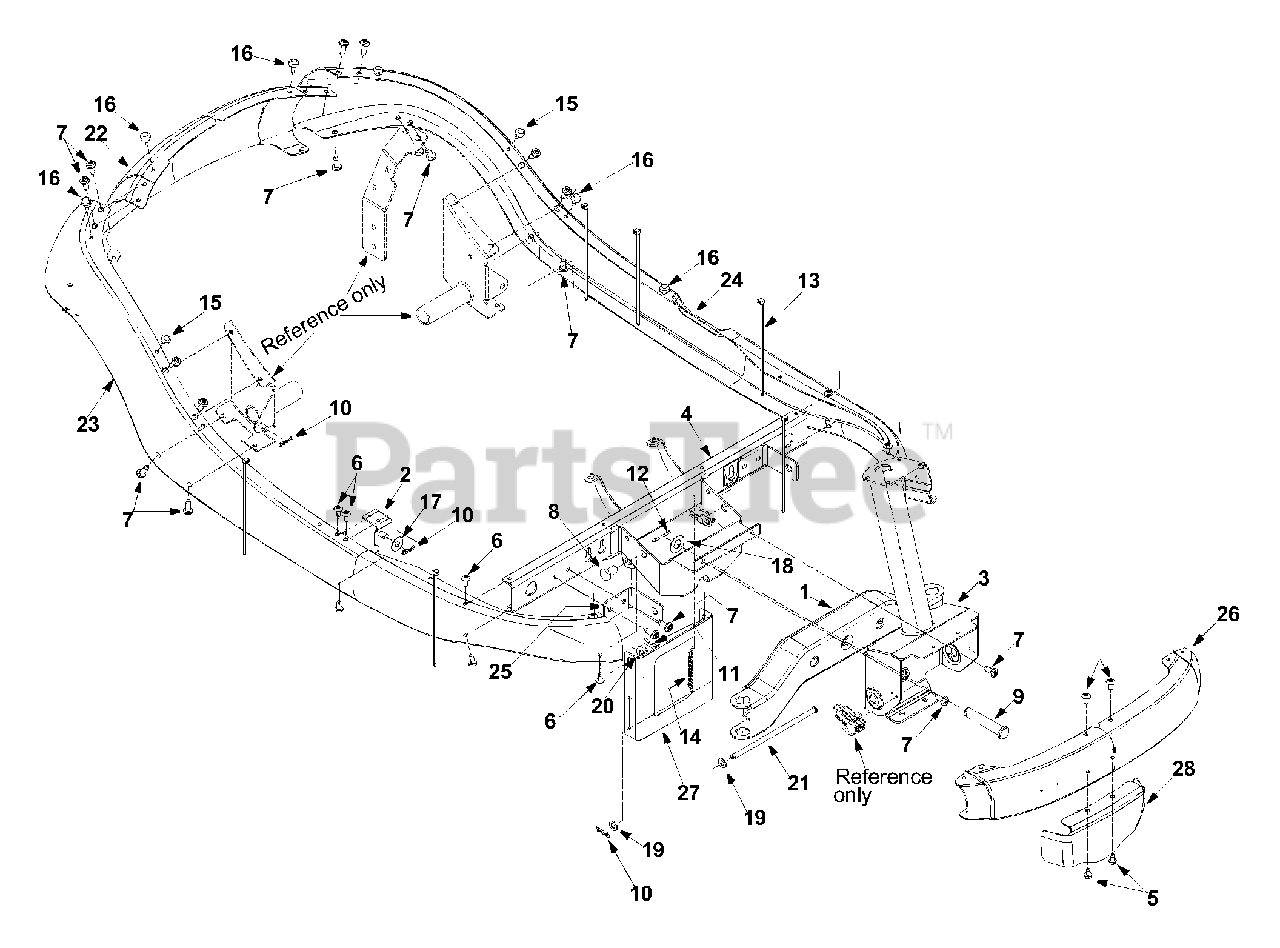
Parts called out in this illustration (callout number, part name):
5	TT screw 1/4-20 x 0.5"
6	AB Screw 1/4-14 x 0.625"
7	TT Screw 5/16-18 x 0.75"
8	Clevis Pin
9	Clevis Pin
10	Cotter Pin
11	Hairpin Clip
12	Cotter Pin
13	Cable Tie
14	Extension Spring
15	Rubber Bumper
16	Bumper
17	Flat Washer
18	Flat Washer
19	Flat Washer
20	Flat Washer
21	Deck Rod
